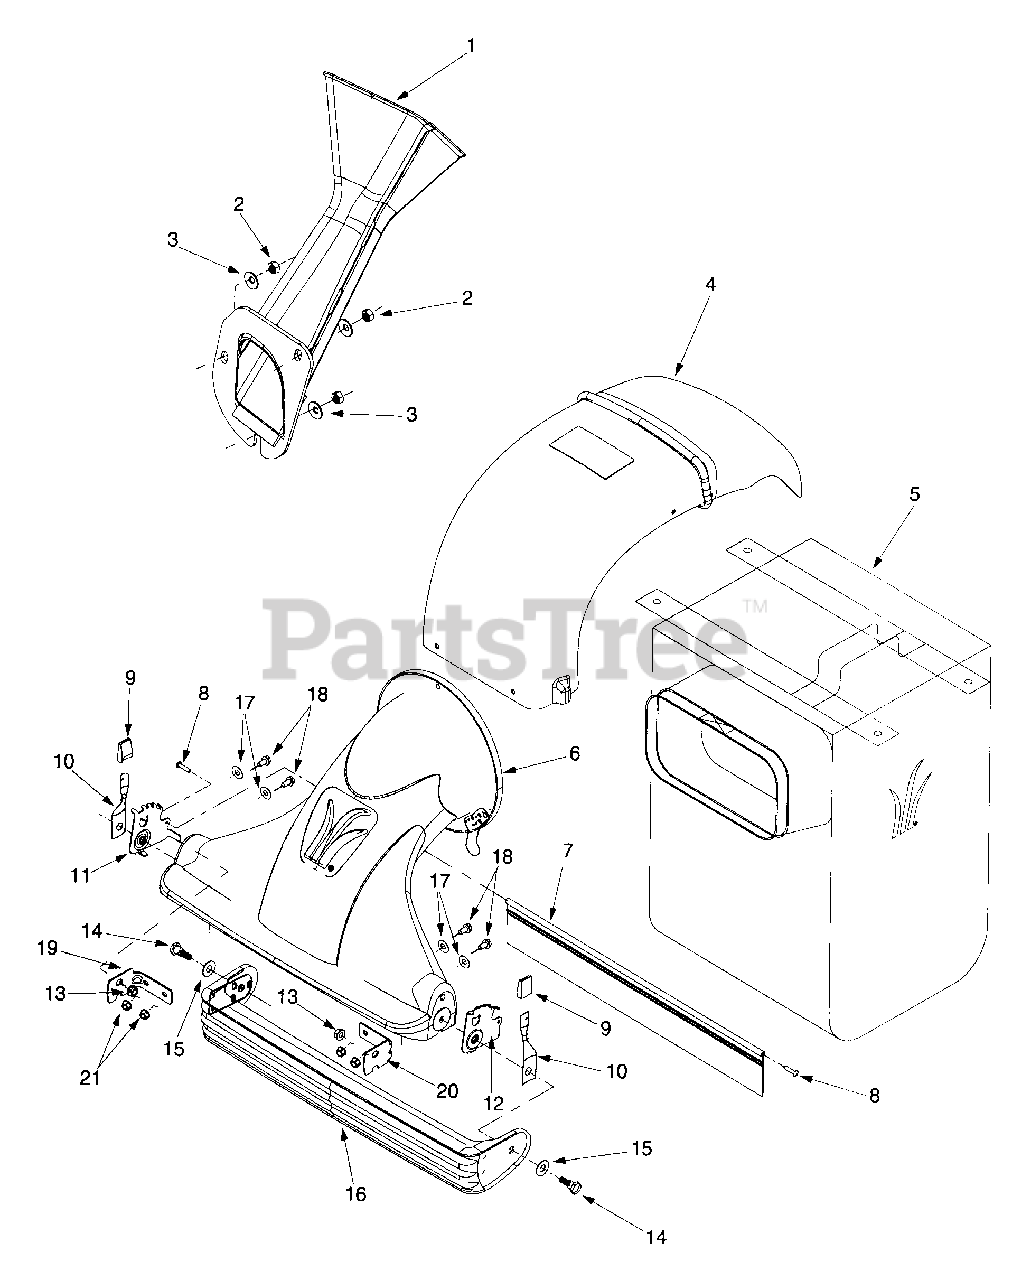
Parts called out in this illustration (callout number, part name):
2	Hex Nut 5/16-18
3	Bell Washer .340 ID x .872 OD
4	Discharge Chute
6	Nozzle Asm
7	Nozzle Flap
8	Screw
9	Height Adjustment Knob
10	Spring Lever
11	Index Bracket RH
12	Index Bracket LH
13	Hex Flange Lock Nut 3/8-16
14	Shoulder Screw
15	Flat Washer .510 x 1.12 x .060
16	Door Asm
17	Flat Washer .28 ID x .74 OD
18	Hex Cap Screw 1/4-20 x .625
19	Nozzle Reinforcement Bracket RH
20	Nozzle Reinforcement Bracket LH
21	Hex Flange Lock Nut 1/4-20
